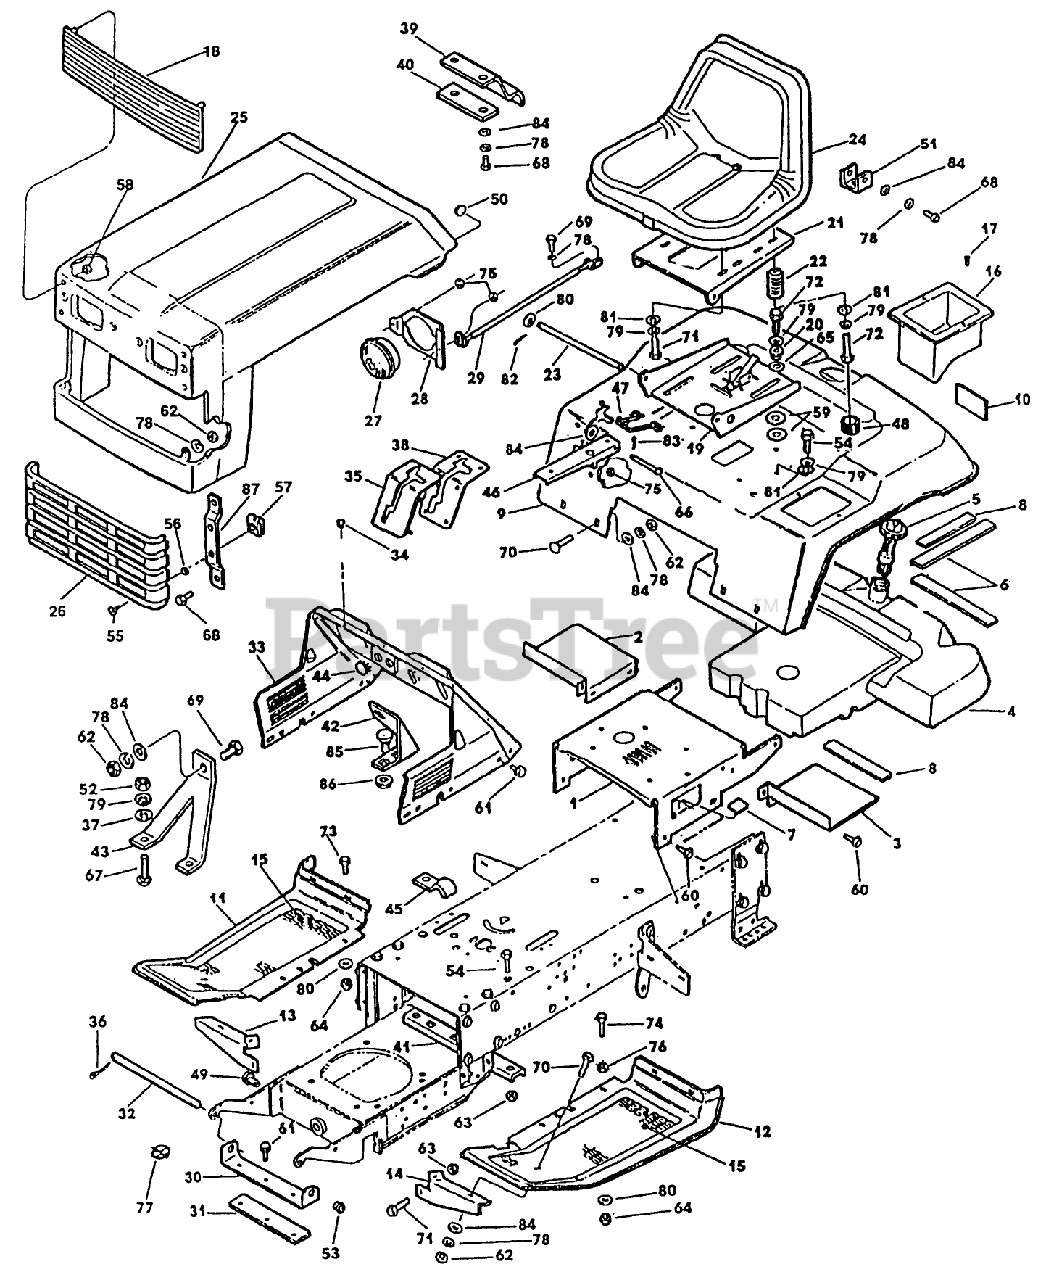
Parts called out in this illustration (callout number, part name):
4	TANK - FUEL
5	GUAGE ASSEMBLY-FUE
8	PAD - FUEL TANK
10	REFLECTOR
11	FOOTREST - RH *G
17	Rivet
19	SEAT SUPPORT AY
21	PIVOT AY - SEAT *B
23	PIN
24	SEAT
25	HOOD GRILLE WLDMT *G
26	INSERT - GRILLE
32	ROD - HOOD PIVOT
43	BRACKET-SUPPORT
46	LATCH - SEAT PAN *B
48	CAP-PROTECTOR
52	NUT SS
53	BEARING-NYLINER
55	FASTENER-1/4 TURN
59	WASHER-PLASTIC
62	NUT
63	NUT
64	NUT-LOCKING
66	PIN
67	BOLT - CARRIAGE
68	SCREW-HH
69	SCREW
71	SCREW - HEX
72	SCREW
76	NUT
77	CLIP-RETAINER, WIRE
80	WASHER
